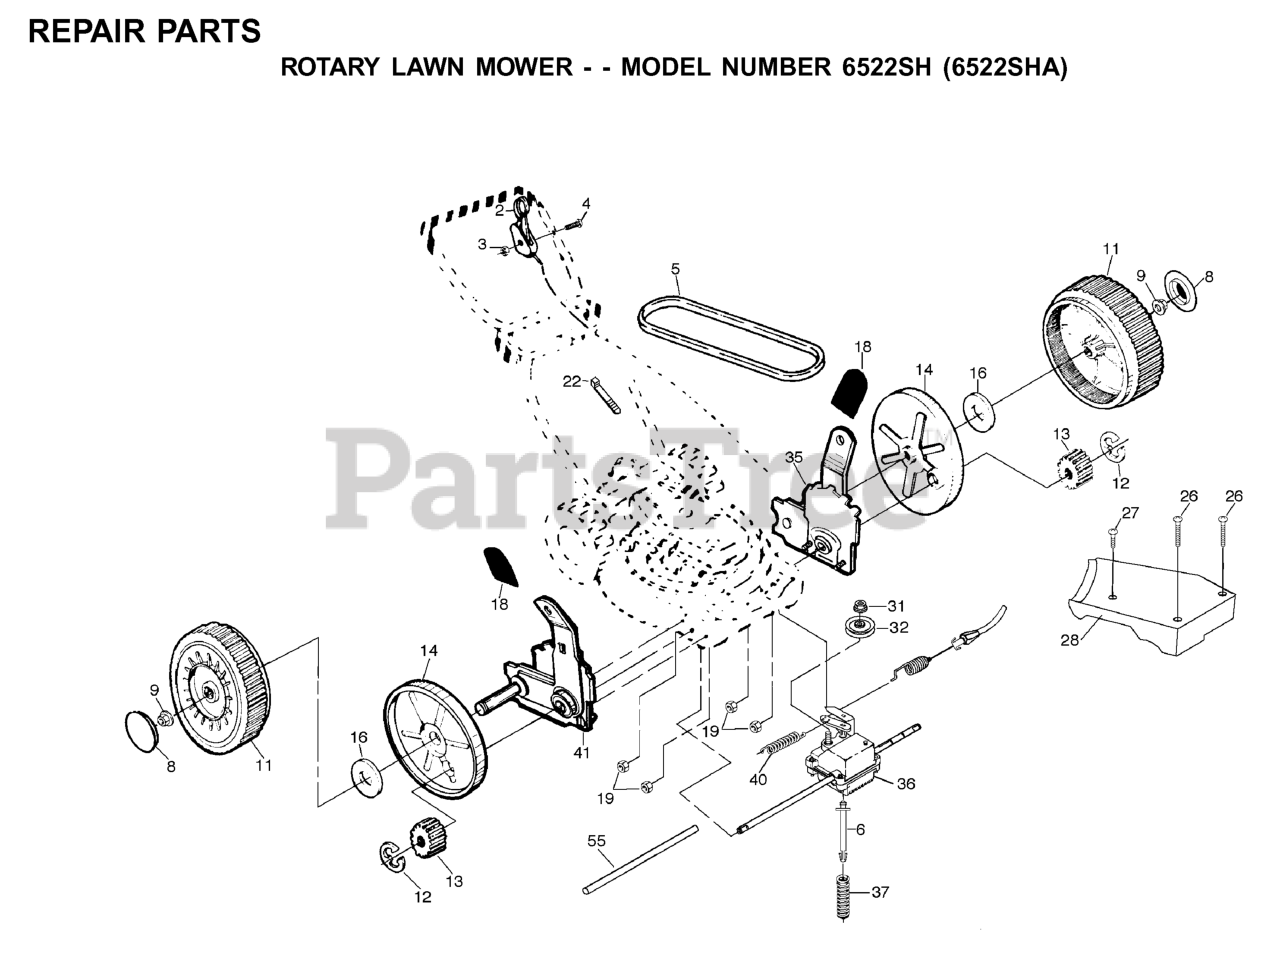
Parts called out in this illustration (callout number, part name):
2	CONTROL
3	LOCK NUT
4	SCREW.PAN.HEAD
5	BELT THERM .32
6	SPRING RETAINER
8	CAP.HUB.BLACK.WALK
9	NUT
12	E-RING 7/16 RE
13	PINION GEAR
14	DUST SHROUD PM
16	WASHER FLUT
19	NUT
22	TIE GUIDE
27	TAPPING SCREW
28	COVER DRIVE
31	FLANGED LOCKNUT 3/8-16 ZINC
32	PULLEY
35	WHEEL ADJ ASM (L)
36	GEAR CASE ASMBLY
37	SPRING.EXTENSION
41	KIT.ADJUSTER.ASM.(151514).RT
55	DRV SHAFT TUBE PM
